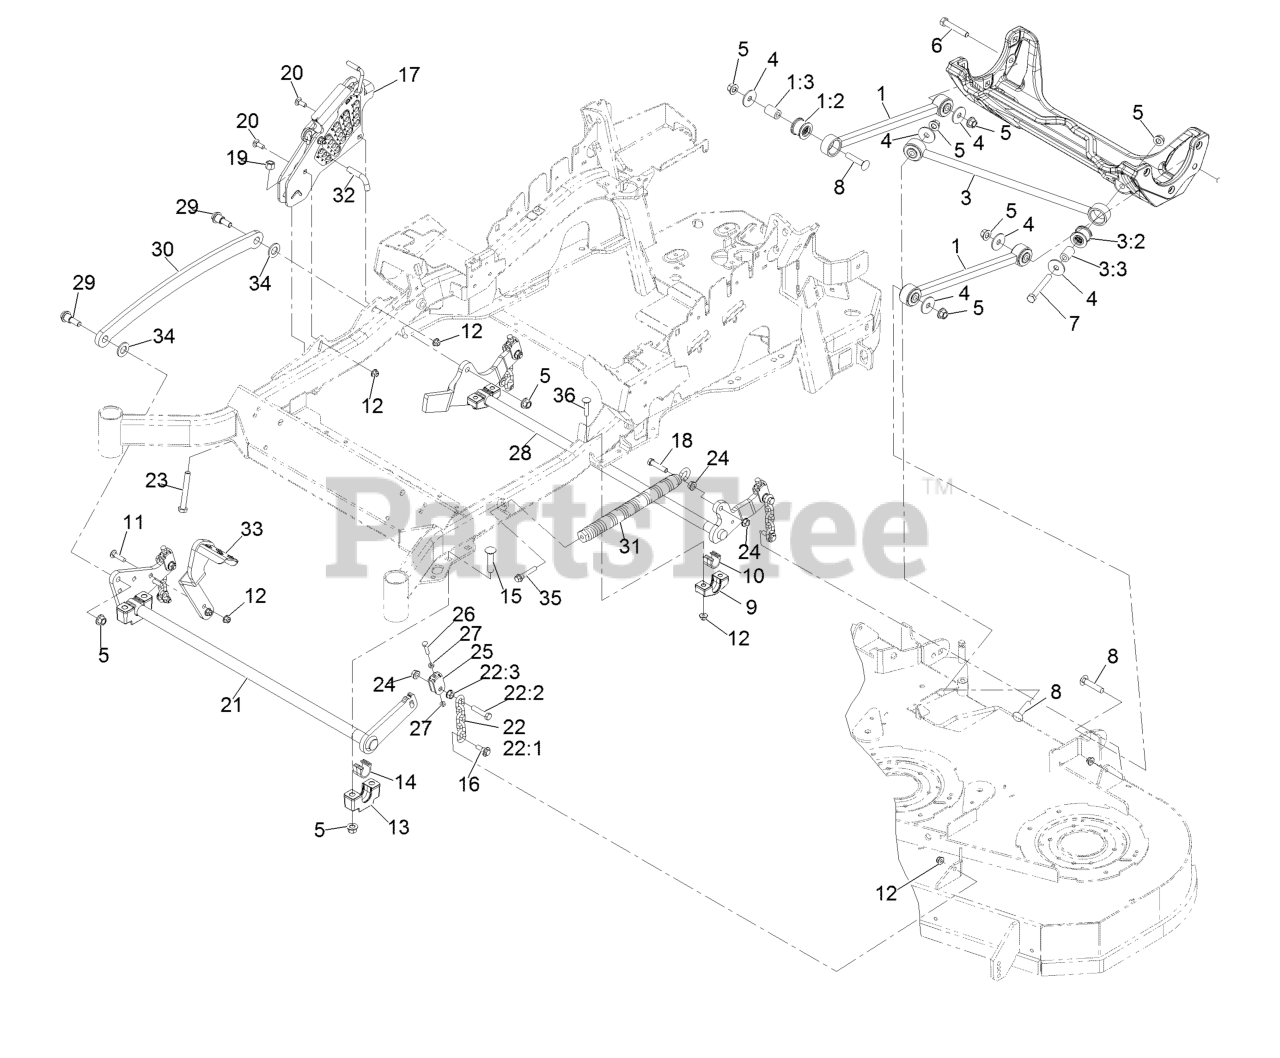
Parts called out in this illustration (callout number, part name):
1	Long Strut ASM
1:2	Bushing-Suspension, Rubber
3	Panhard Rod ASM
3:2	Bushing-Suspension, Rubber
5	Nut-Lock 1/2-13
6	Screw-HH 1/2-13 X 3
7	Screw-HH 1/2-13 X 4
8	Bolt-Carriage 1/2-13 X 2 1/2
9	Support-Cross Shaft, Bearing Rear
10	Bearing-Cross Shaft, Rear
11	Bolt-Carriage 3/8-16 X 1 1/2
12	Nut-Nyloc 3/8-16 Flg
13	Support-Cross Shaft, Bearing
14	Bearing-Cross Shaft, Front
15	Bolt-Carriage 1/2-13 X 2 1/2 Spl Neck
16	Screw-Hex Flange 3/8-16 X .80
17	HOC ASM
18	Screw-HH 7/16-14 X 2
19	Nut-Nyloc 1/2-13
20	Bolt-Carriage 3/8-16 X 1
21	Decklift-Front
22	Deck Lift Chain ASM
22:1	Chain-Lift, Deck
22:2	Screw-HH 7/16-14 X 2
22:3	Nut-Whizlock 7/16-14
23	Bolt-HH 1/2-13 X 4 Tap
24	Nut-Whizlock 7/16-14
25	Yoke-Adjust, Deck
26	Screw-HH 5/16-18 X 1 1/4
27	Nut-Jam 5/16-18
28	Lift-Deck, Rear
29	Screw-Shoulder HHF 1/2-13 X 1.12
30	Link-Lift, Deck
31	Spring-Extension
32	Pin-HOC
33	Lever-Foot
34	Washer-3/4 SAE
35	Screw-Shcs 3/8-16 X 2.212
36	Bolt-Carriage 3/8-16 X 2 1/4
